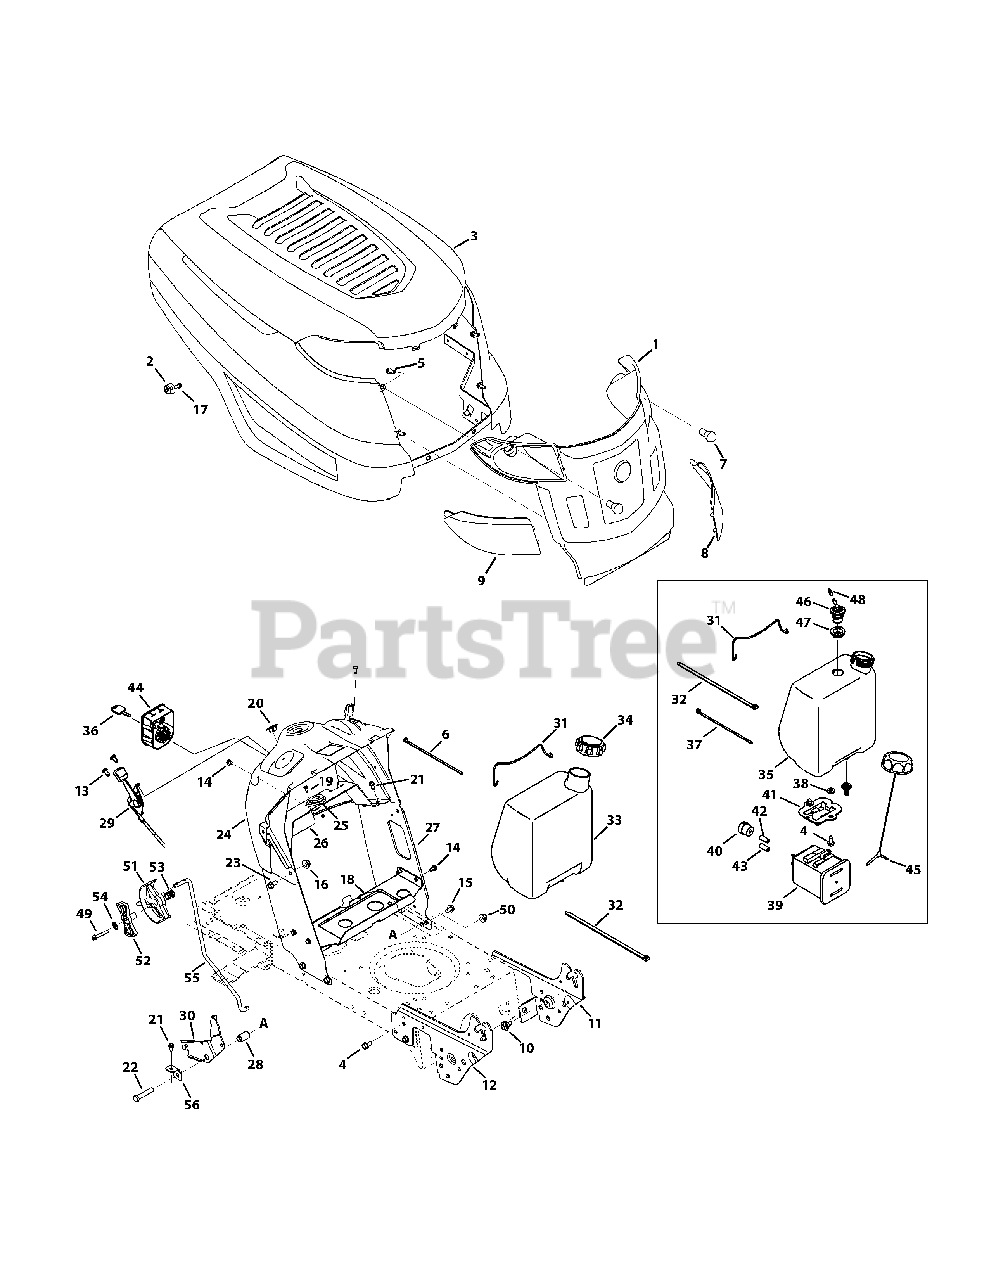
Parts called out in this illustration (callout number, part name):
1	Grill Assembly, Troy-Bilt
2	K-Style Bumper
3	Hood Assembly
4	Screw, 5/16-18 x .750
5	Screw, 1/4-15 x .750
6	Cable Tie
9	Right Lens
10	Shoulder Screw, 5/16-18 x .43 x .29
11	Left Support Pivot Bracket
12	Right Support Pivot Bracket
13	Screw, 1/4-20 x .500
14	Screw, 1/4-20 x .500
15	Screw, 5/16-18 x .625
16	Flangelock Nut, 5/16-18
17	Screw, #12-16 x 1.25
18	Gas Tank Support Bracket
19	Screw, #10-16 x .500
20	Choke Plug
21	Hex Washer Screw, 1/4-20 x .500
22	Hex Screw, 3/8-16 x 2.0
23	Hex Screw, 5/16-18 x .625
24	Dash, Upper
25	Bearing, .628 ID x 1.36
26	Bracket, Steering Support
27	Dash, Lower
28	Flange Spacer, .390 x .671 x 1.095
29	Throttle/Choke Cable
30	Speed Latch - No RMC
31	Battery Assembly Rod
32	Cable Tie
33	1.5 Gallon Fuel Tank
34	Fuel Cap
35	1.36 Gallon Fuel Tank
37	Cable Tie
38	Flat Washer, .344 x .750 x .120
39	5 Gallon Carbon Canister
40	Vent Filter Canister
41	Canister Adapter Bracket
42	Fuel Hose, White
43	Fuel Hose, Yellow
44	3 Position Key Switch
45	Fuel Cap, 2.25"
45	Fuel Cap, 2.25" EPA
46	Rollover Valve
47	Rubber Grommet, 23 x 3.55
48	Hose Vent, 3/16 EPA
49	Hex Washer Screw, 1/4-20 x 1.50
50	Flangelock Nut, 3/8-16
51	Shift Lever
52	Index Control
53	Compression Spring, .72 OD x .78
54	Lock Washer, 1/4
55	Speed Control Rod
56	Speed Latch Tab
